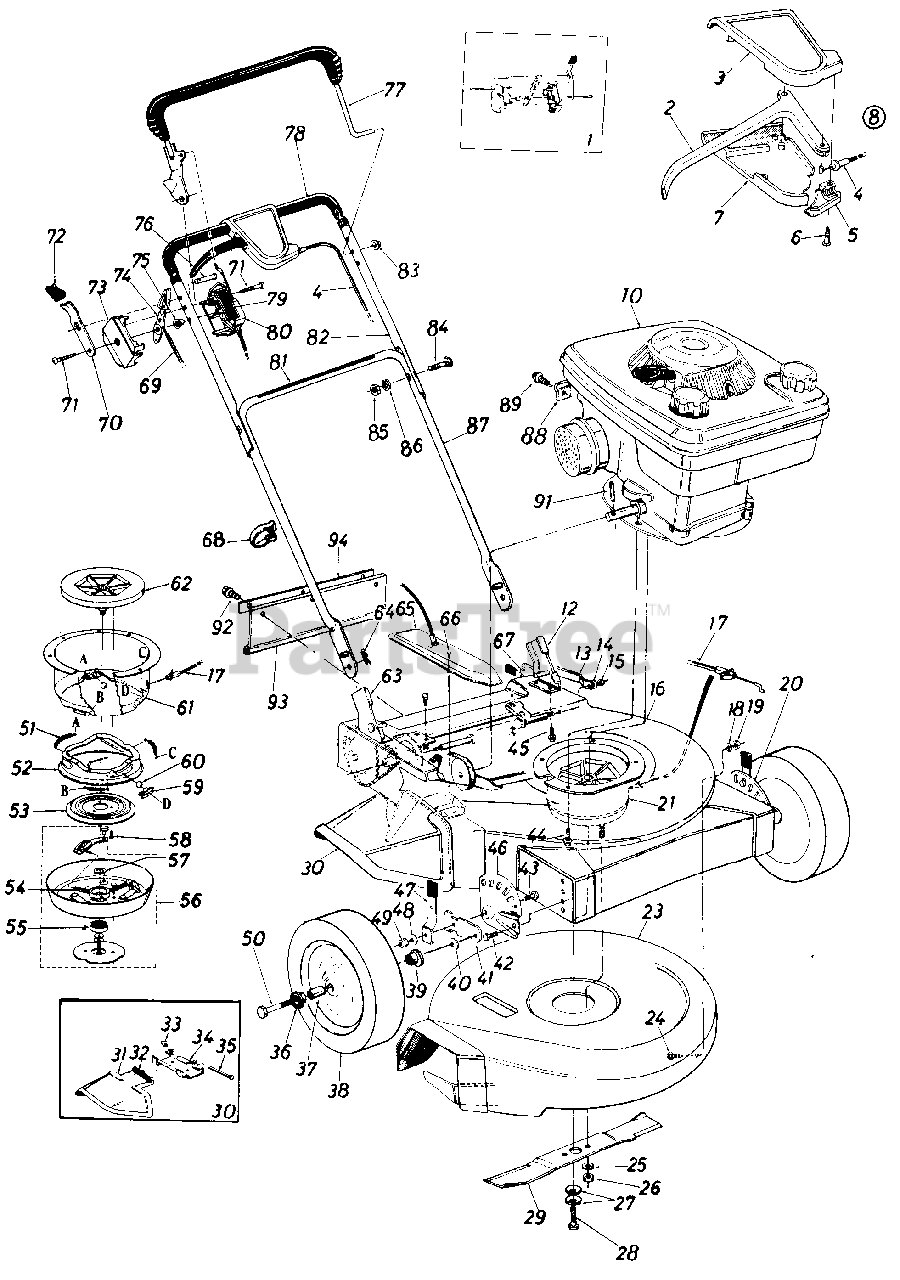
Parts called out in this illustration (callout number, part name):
1	Control Housing Comp.
2	Control Lever
3	Control Cover Half-Upper
4	Drive Clutch Cable-59"
5	Cable Mounting Cap
6	Flat "C" Sunk Hd. Tap Scr. #10 x .75" Lg.
7	Control Cover Half-Lower
8	Clutch Control Housing Comp.
10	Engine
12	Handle Mount Brkt. Ass'y.-L. H .
13	Pivot Brkt. Ass'y.-L.H.
14	Belleville Wash. .400 I.D. x .8
15	Hex Nut 5/16-18 Thd.
18	L-Wash. 5/16 I.D.
19	Hex Nut 5/16-18 Thd.
20	Height Adj. Ass'y. Comp.-L. H .
21	Blade Brakel Clutch Ass'y.-Comp.
23	Lower Deck Ass'y.
24	Carriage Bolt 5/16-18 x .62
25	L-Wash. 3/8" I.D.
26	Hex Nut 8/8-24 Thd. (Grade 8)
27	Belleville Wash.
28	Hex Bolt 818-24 x 2.00 Lg. (Grade 8)
29	21" Blade
30	Chute Deflector Ass'y.-Comp.
31	Chute Deflector
32	Torsion Spring
33	Push Nut 1/4" Rod
34	Adapter Plate
35	Pivot Pin
36	Ball Bearing 3/8" I.D.
37	Spacer
38	Wheel Ass'y. Comp. 8 x 1.75
39	Ball Bearing 1/2" I.D.
40	Bell-Wash. .400 I.D. x .88"
41	Pivot Bar
42	Hex Sems Bolt 8/8-16 x .62
43	Shoulder Bolt
44	Hex Wash. Hd. TT-Tap Scr. 3/8-16x 1" Lg.
45	Hex Wash. Hd. "B"-Tap Scr. 5/16 x 1/2" Lg.
46	Height Adjuster Ass'y. Comp.-R.H.
47	Spring Lever Ass'y. w/Knob
48	Bell-Wash. .400" I.D. x 1.13"
49	Hex Ins. L-Nut 3/8-24 Thd.
50	Axle Bolt
51	Extension Spring
52	Brake Cup Cone
53	Clutching Cone
54	Compression Spring
55	Ball Bearing
56	Clutch Blade Housing Ass'y.
57	Fl-Wash. .69" I.D. x 1.06" O.D.
58	Hex TT-Tap L-Scr. 1/4-20 x .75" Lg.
59	Ball Block
60	Steel Ball 1/2" Dia.
61	Clutch Housing
62	Fan Adapter
63	Handle Mount Brkt. Ass'y.-R.H. I
64	Internal Cotter Pin 5/16" Dia.
65	Belt Cover
66	Hex Wash. Hd. "AB" Tap Scr. #10 x .50" Lg.
67	Index Plate Ass'y.-L.H.
68	Cable Tie
69	Throttle Wire-43"
70	Lockout Spring
71	Truss Mach. Tap Scr. #12 x 1.5" Lg.
72	Spring Lever Knob
73	Control Panel Half
74	Throttle Control Lever
75	Control Disc Pin
76	Lock Pin
77	Control Handle-R.H.
79	Control Label-Throttle
80	Clutch Panel Half
81	Instruction Label-Handle
82	Upper Handle (Chrome)
83	Cap Speed Nut 5/16" Rod
84	Curved Carriage Bolt 5/16-18 x 1.38" Lg.
85	Hex Nut 5/16-18 Thd.
86	L-Wash. 5/16" I.D.
87	Lower Handle (Chrome)
88	Casing Clamp
89	Hex Sems Scr. #10-32 x .62" Lg.
91	Spring Pin 3/16" Dia. x 1.5" Lg.
92	Hex Wash. Hd. AB-Tap Scr. 1/4 x.62" Lg.
93	Rear Flap
94	Retaining Strip
